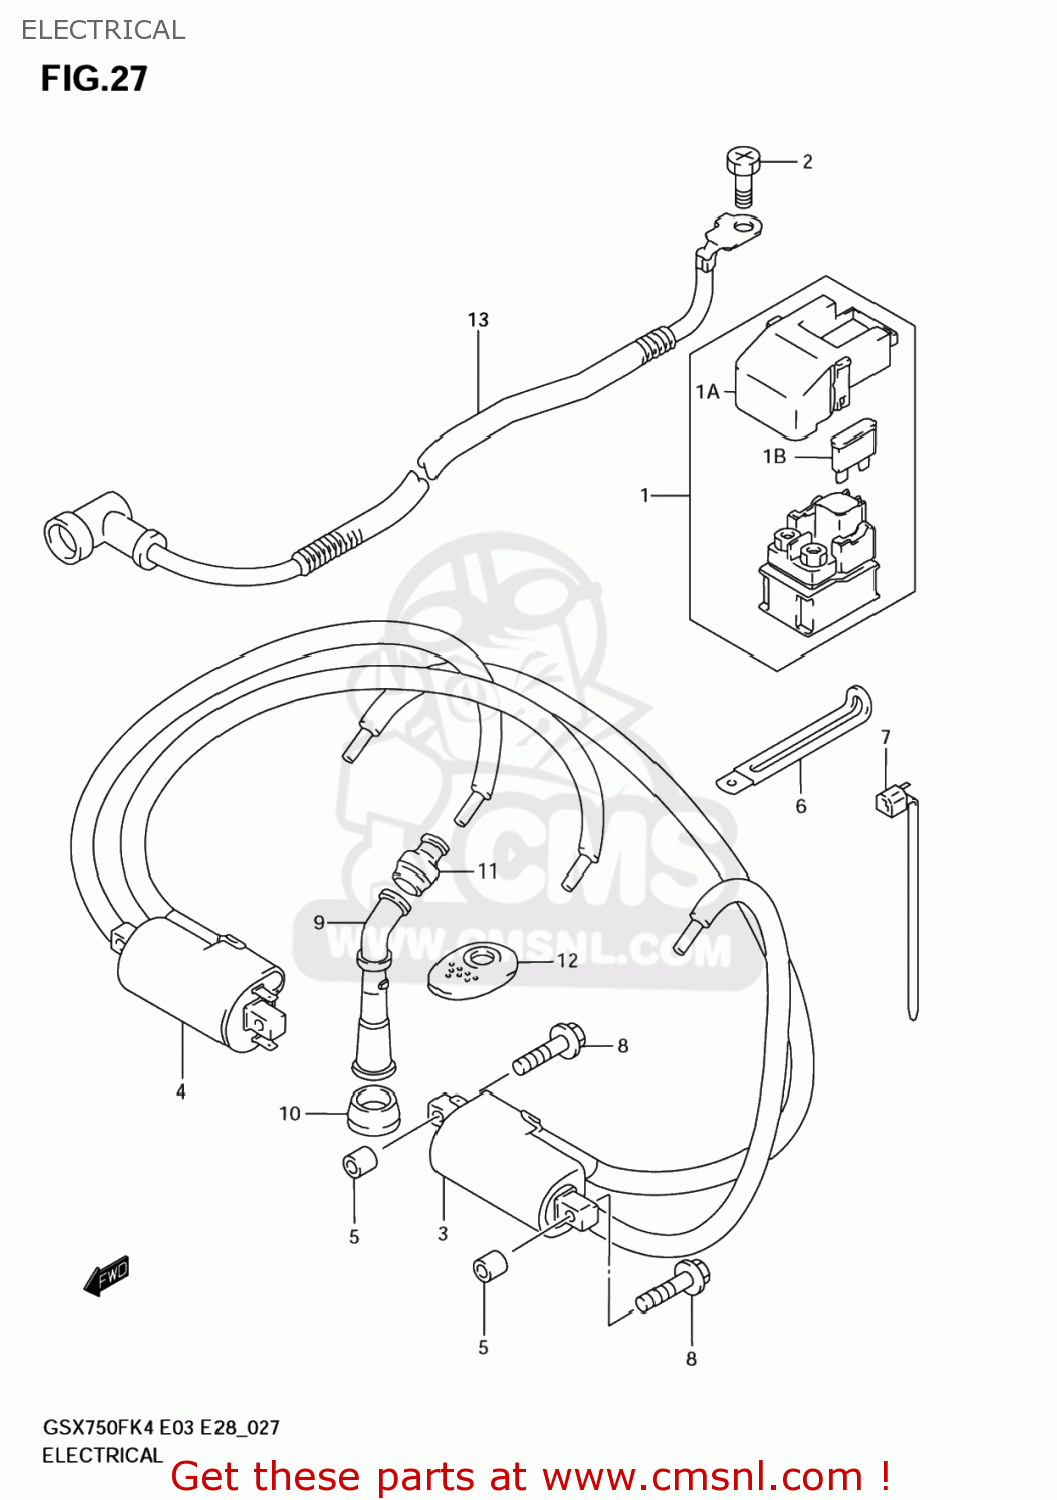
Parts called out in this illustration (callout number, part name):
1	RELAY ASSY,STARTING MOTOR
1A	COVER
1B	FUSE(30A)
2	SCREW(6X8)
3	COIL ASSY,IGNITION
4	COIL ASSY,IGNITION
5	SPACER(6.2X12X14)
6	CLAMP(L:80)
7	CLAMP(L:165)
8	BOLT (6X45)
9	CAP,SPARK PLUG
10	SEAL,SPARK PLUG CAP
11	SEAL,HIGH TENSION CORD
12	COVER,SPARK PLUG CAP
13	WIRE,BATTERY MINUS
